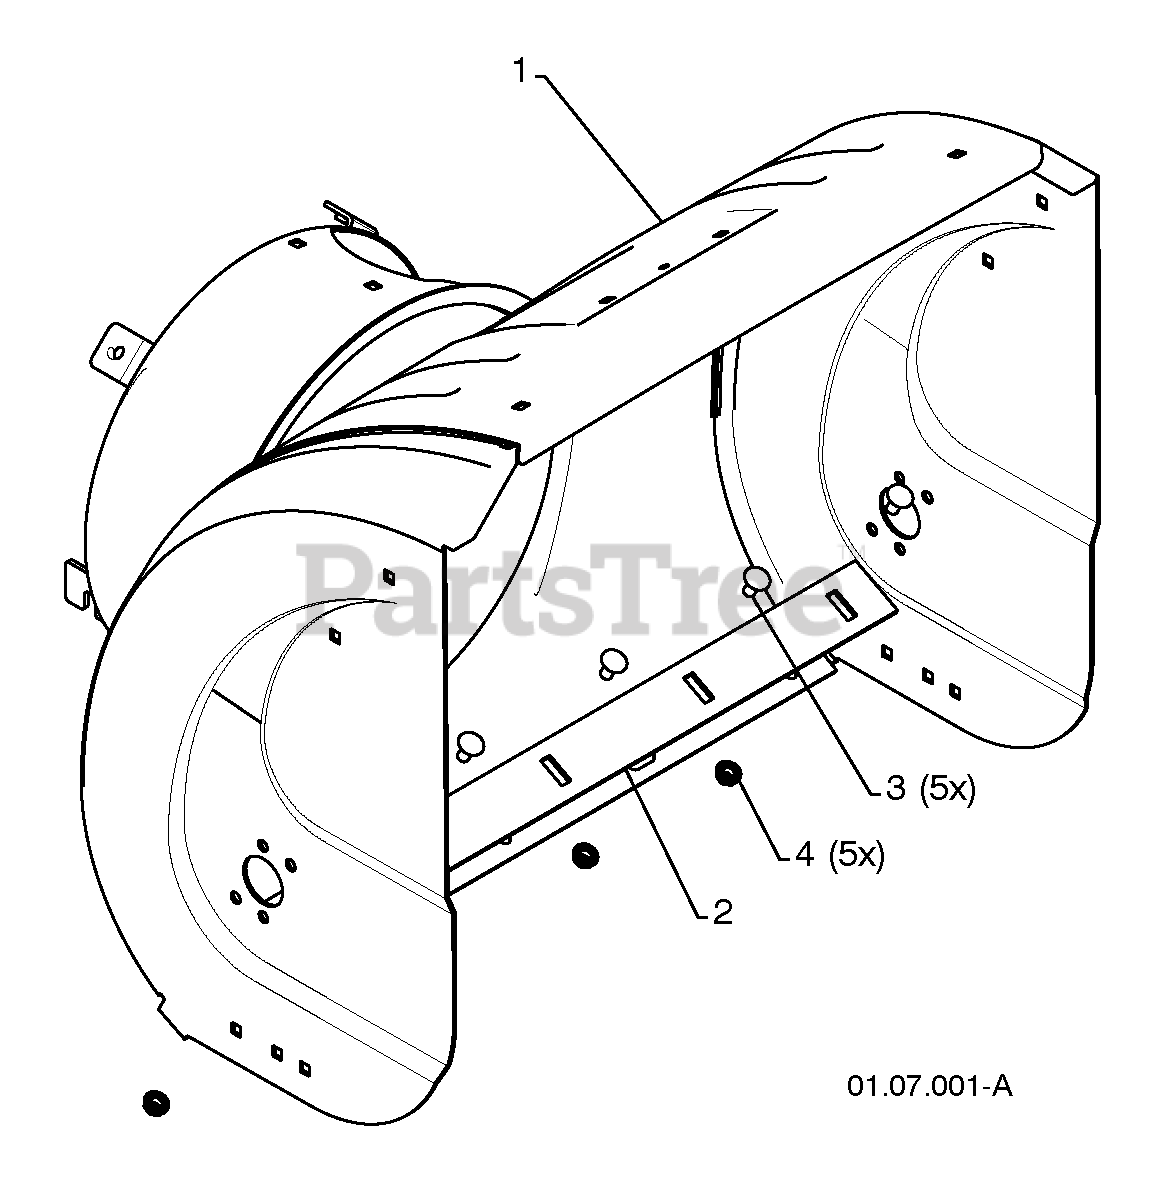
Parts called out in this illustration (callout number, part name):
1	AUGER HOUSING
2	SCRAPPER BAR
3	CARRIAGE BOLT 5/16-18 X .625
4	NUT 5/16-18
